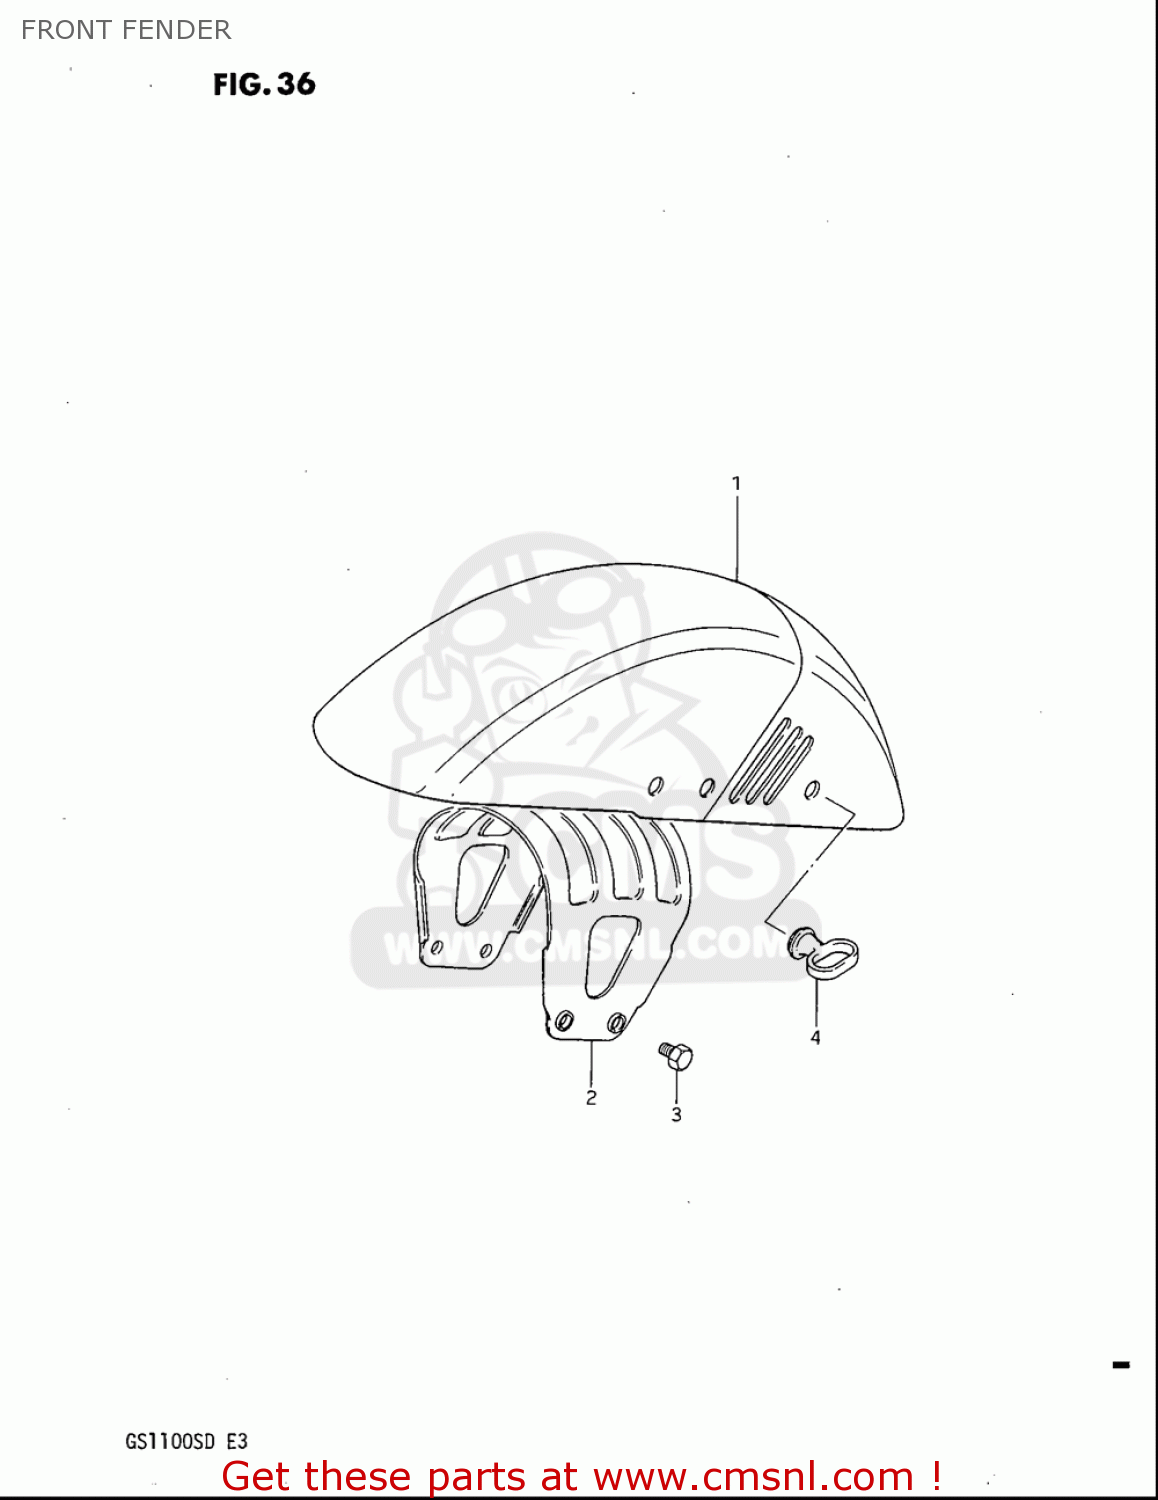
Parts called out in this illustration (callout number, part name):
1	FENDER,FR
2	BRACE,FR FENDER CTR
3	BOLT(8X16)
4	GUIDE,CABLE
